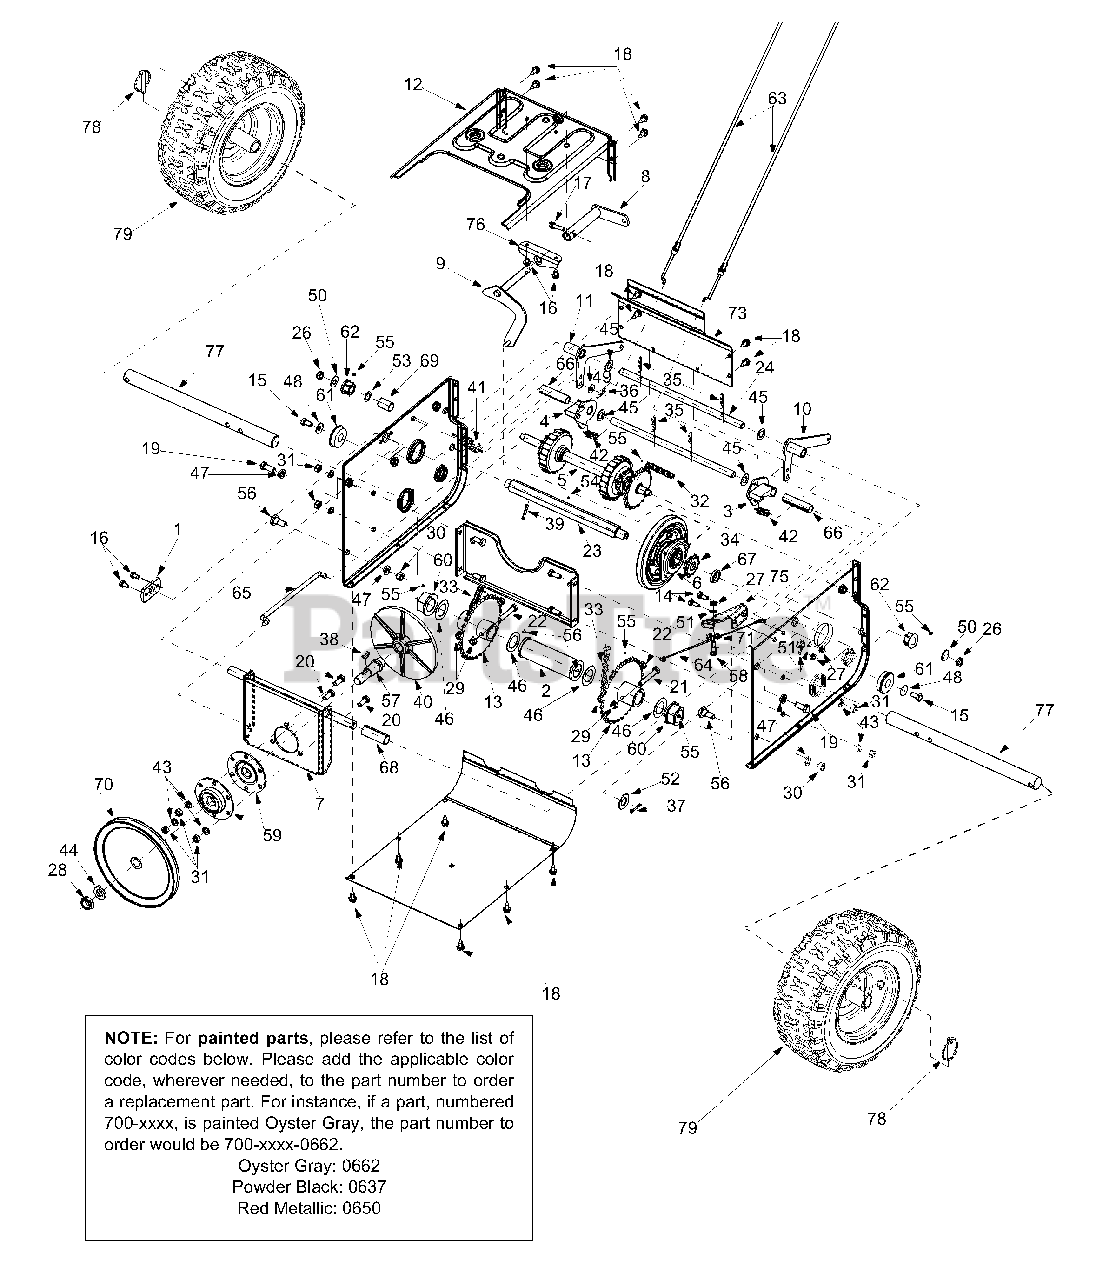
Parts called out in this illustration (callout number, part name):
1	Support Bracket: Pivot
2	Bush Assembly
3	Dogg Assembly LH
4	Dogg Assembly RH
5	Shift Assembly
6	Wheel Bearing Assembly
7	Support Bracket Assembly
10	Auger Actuator Bracket Assy.
11	Drive Actuator Bracket Assy.
14	Hex Screw 1/4-28 x .625"
15	Hex Screw 5/16-18 x .625"
16	TT Screw 1/4-20 x .5"
17	TT Screw 1/4-20 x 1"
18	TT Screw 1/4-20 x .625"
19	Hex Screw 3/8-16 x .880"
20	Hex Screw 5/16-18 x .75"
21	Hex Screw 5/16-18 x 2"
22	Hex Screw 5/16-18 x 1.75"
23	Hex Shaft: Drive
24	Actuator Shaft
26	Lock Nut
27	Hex Nut 1/4-28
28	Jam Lock Nut
29	Hex Lock Nut
30	Hex Nut 3/8-16
31	Hex Nut 5/16-18
32	Chain
33	Chain
34	Sprocket
35	Hairpin Clip
36	Hairpin Clip
37	Cotter Pin
39	Roll Pin
40	Drive Plate
41	Extension Spring
42	Extension Spring
43	Lock Washer 5/16
44	Lock Washer 5/8
45	Flat Washer
46	Flat Washer
47	Lock Washer
48	Beleville Washer
49	Flat Washer
50	Flat Washer
51	Lock Washer
52	Flat Washer
53	Flat Washer
54	Lubricant
55	Grease
56	Shoulder Screw
57	Spindle: Drive Plate
58	Shoulder Screw 1/4-28 x .375"
59	Bearing Housing Assembly
60	Flange Bearing
61	Ball Bearing
62	Hex Flange Bearing
63	Steer Cable
64	Idler Cable: Auger
65	Clutch Rod: Drive
66	Split Spacer
67	Spacer
68	Split Spacer
69	Spacer
70	Drive Pulley
71	Roller Cable
72	Frame Support Bracket
77	Axle: Wheel
78	Klik Pin
